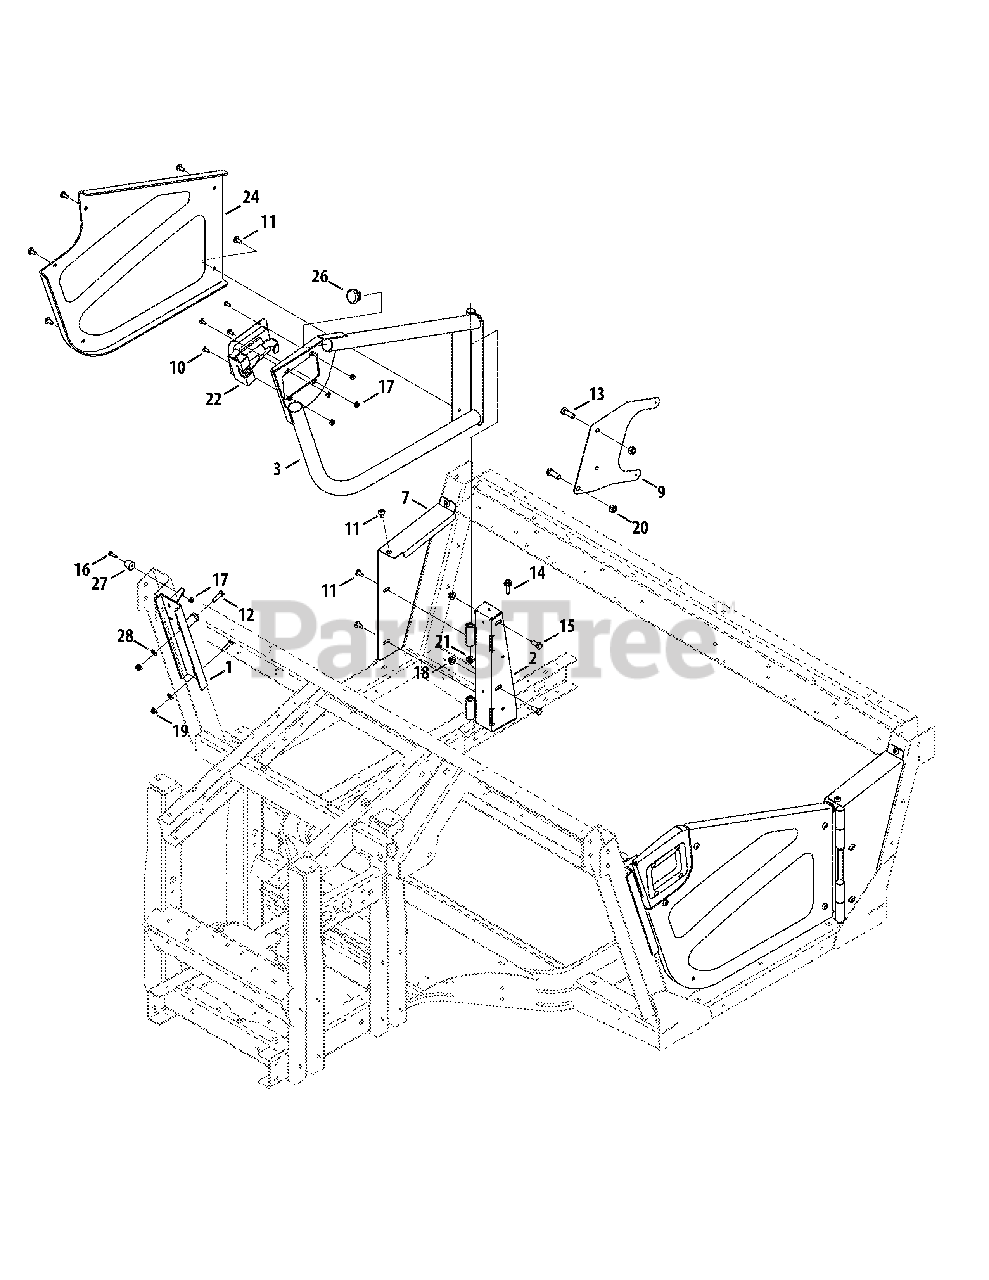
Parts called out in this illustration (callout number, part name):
1	Bracket Assembly, Strike Bolt, LH
1	Bracket Assembly, Strike Bolt, RH
2	Bracket Assembly, Hinge, LH
2	Bracket Assembly, Hinge, RH
3	Door Assembly, LH
6	Door Assembly, RH
7	Cover, Hinge, LH
7	Cover, Hinge, RH
9	Template, Hinge Mount
10	Screw, #10-24 x .500
11	Screw, 1/4-20 x .500
12	Hex Cap Screw, 1/4-20 x 1.00
13	Hex Cap Screw, 3/8-16 x 1.00
14	Screw, 5/16-18 x 1.00
15	SCREW 5/16-18 x .75 GR5
16	Screw, #10-24 x .75
17	Nut, #10-24
18	Nut, 5/16-18
19	Nut, 1/4-20
20	Nut, 3/8-16
21	Cap, Push, 3/8
22	Latch, Door, stamped LT
22	Latch, Door, stamped RT
24	Panel, Door, LH
24	Panel, Door, RH
26	Plug, 1.25
27	Rubber Bumper
28	Washer, .28 x .74 x .063
